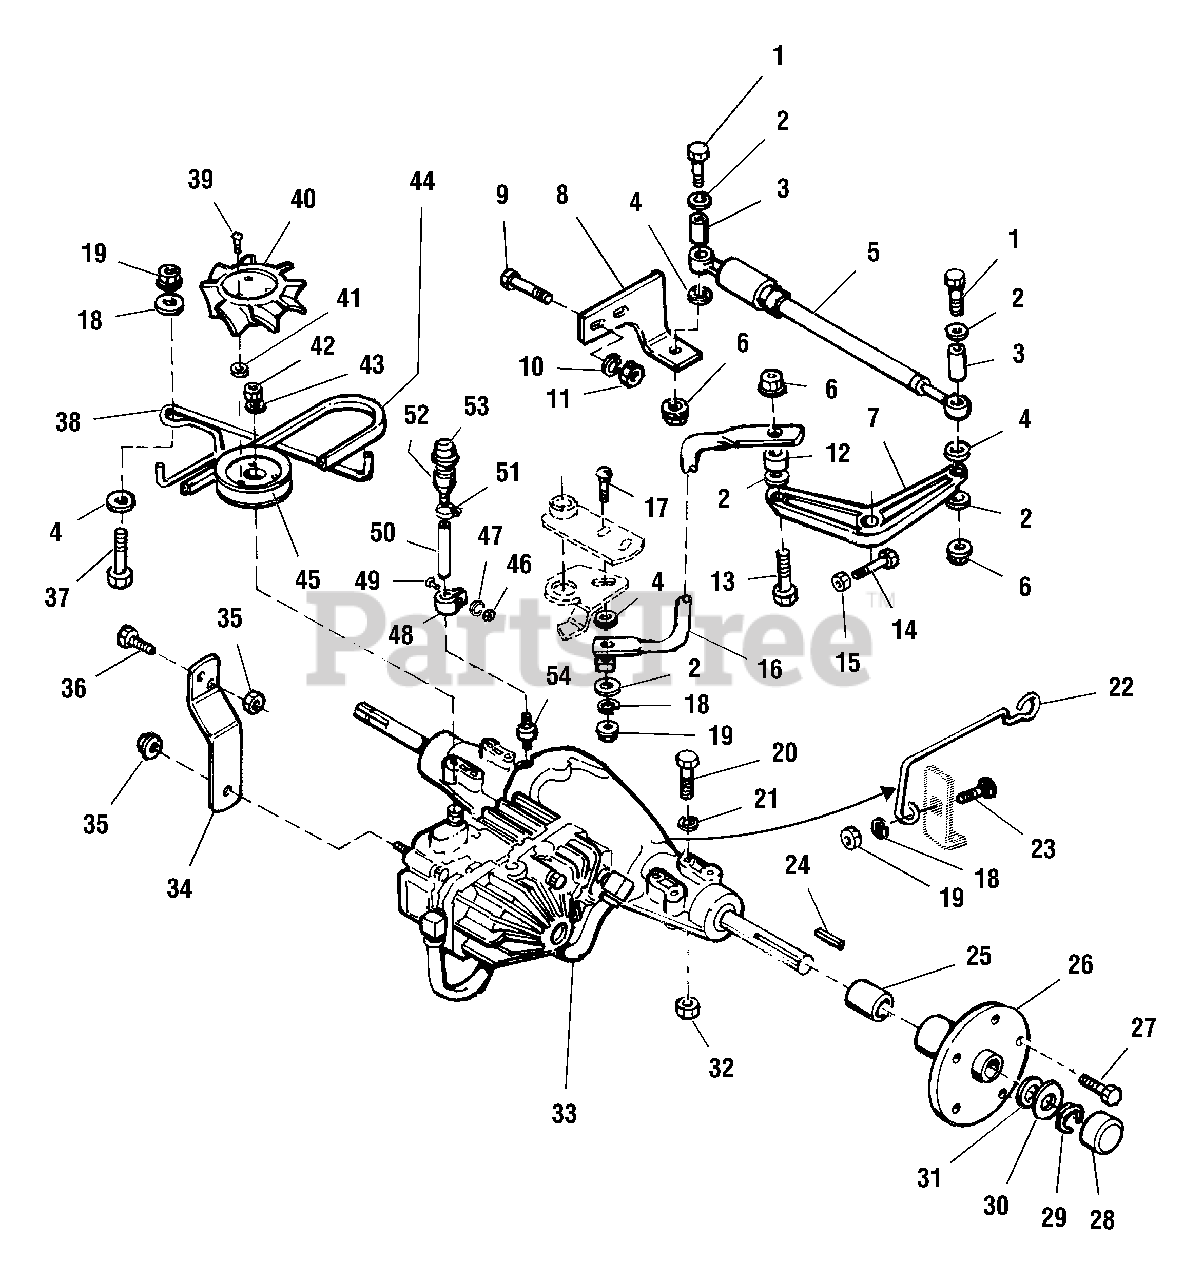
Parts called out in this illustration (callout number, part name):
1	CAPSCREW, Hex Head 5/16-18 x 2 G5
2	WASHER, 11/32 x 3/4 x 1/16
4	WASHER, 11/32 x 1 x 1/8
5	SHOCK ABSORBER
6	NUT, Hex Flange Lock, 5/16-18
7	LEVER, Hydro Control
8	BRACKET, Shock
9	CAPSCREW, Hex Hd., 3/8-16 x 1
10	LOCKWASHER, 3/8
11	NUT, Hex.Fin., 3/8-16
13	CAPSCREW, Hex Hd., 5/16-18 x 3/4
14	SCREW, Hex Soc. Hd., Gr. 8 #10-32 x 2
15	NUT, Hex Lock #10-32
16	ROD, Shift, Rear
17	BOLT, Carriage, 5/16-18 x 1-1/4
18	LOCKWASHER, 5/16
19	NUT, Hex Fin., 5/16-18
20	CAPSCREW, 3/8-16 x 3-1/4
21	WASHER, 13/32 x 1 x 1/8
22	LEVER, Hydro Release Valve
23	BOLT, Carriage, 5/16-18 x 3/4
24	KEY, 1/4 x 1/4 x 2-1/4
26	HUB ASSY., Rear Wheel
27	BOLT, Hub, Rear Wheel
29	RING, "E" Retaining
30	WASHER, Retainer, Hub Cap
31	WASHER, 1-1/32 x 1-5/8 x 1/16
32	NUT, Hex Flange Lock, 3/8-16
33	HYDROSTATIC PUMP & TRANSAXLE ASSY.
34	SUPPORT, Transmission
35	NUT, Hex Whiz Lock, 5/16-18
36	SCREW, Whizlock, 5/16-18 x 3/4
37	CAPSCREW, Hex Hd., 5/16-18 x 1-1/4
39	SCREW, Taptite, 1/4-20 x 1-1/64
41	WASHER, 17/64 x 5/8 x 3/64
42	NUT, Hex Jam, 9/16-18
43	LOCKWASHER, 9/16
44	V-BELT, 86.25"
45	PULLEY ASSY., Transmission
46	NUT, Hex Fin. 1/4-20
47	LOCKWASHER, 1/4
49	CAPSCREW, Hex Hd., 1/4-20 x 3/4
52	NECK, Filler
53	CAP, Filler
54	FITTING, Vent Tube
